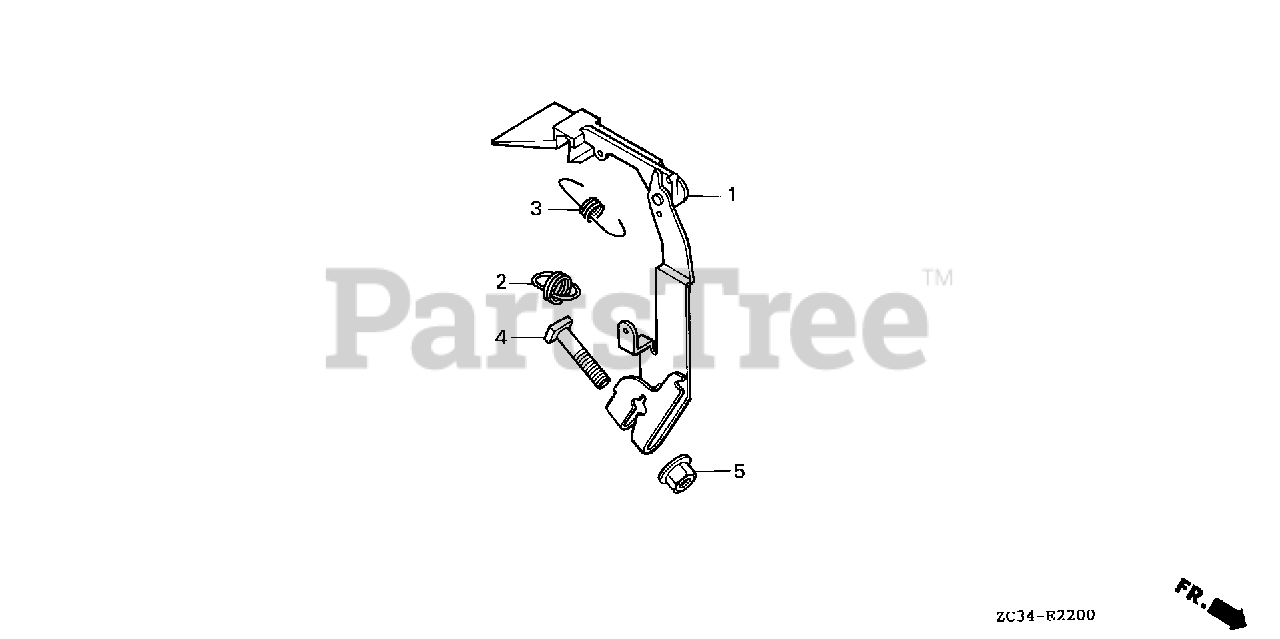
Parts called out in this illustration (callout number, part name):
1	ARM, GOVERNOR
2	SPRING, GOVERNOR (NOT AVAILABLE)
3	SPRING, THROTTLE RETURN
4	BOLT, GOVERNOR ARM (5MM)
5	NUT, FLANGE (5MM)
